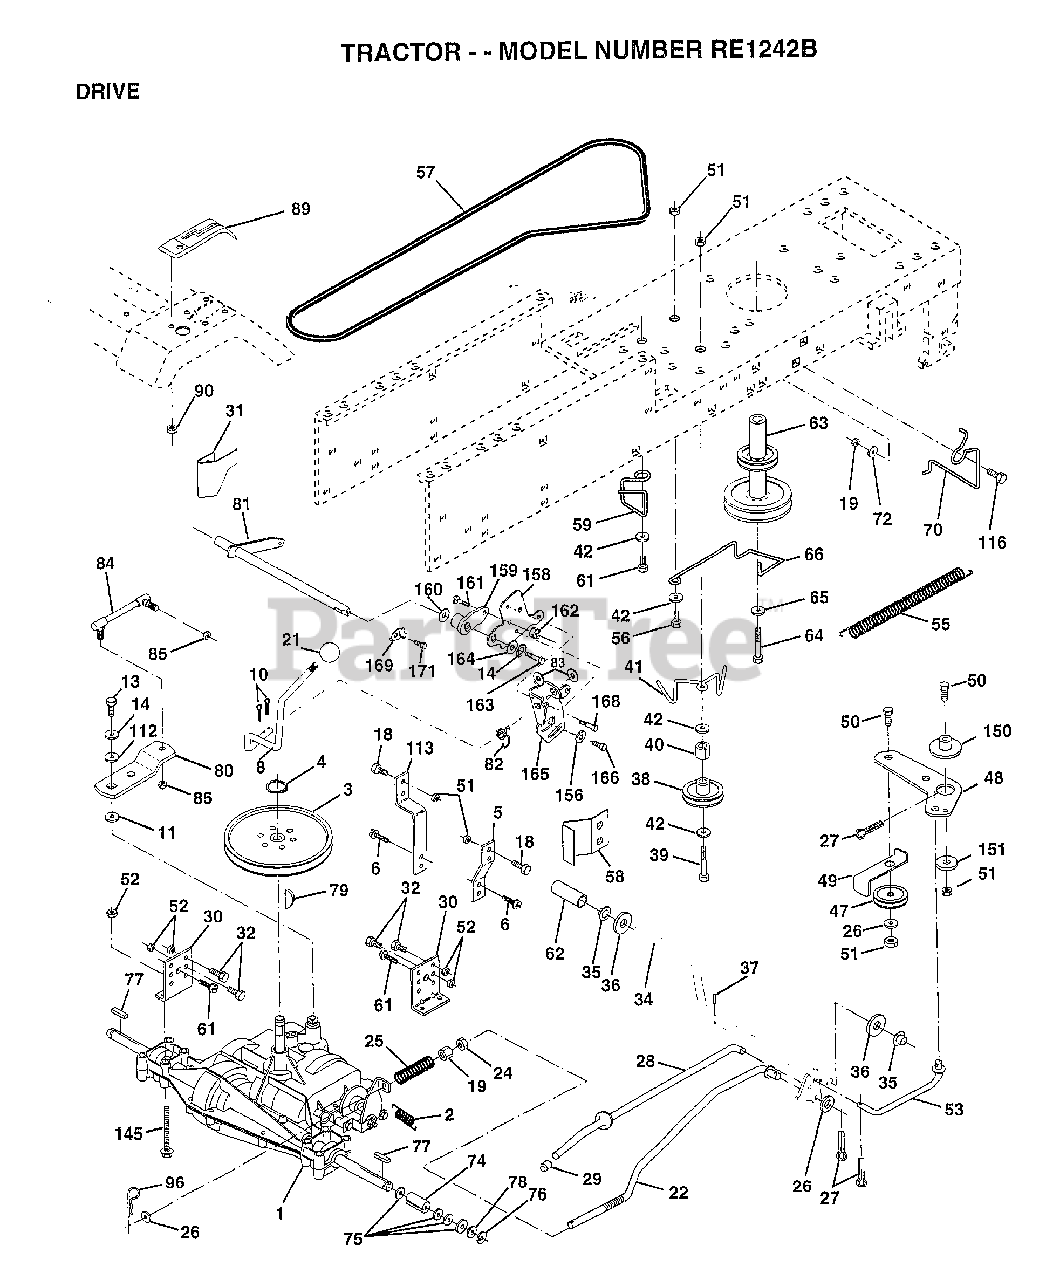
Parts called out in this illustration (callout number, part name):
2	SPRING.BRAKE.RETU
3	PULLEY TRANS
5	STRAP TORQUE
6	SCREW
8	ROD.SHIFT.FENDER.ADJ.LT.CRD
10	PIN COTTER 1/8
11	WASH-SHFT PLT LT
13	BOLT.1/4-28.W/PAT
14	LOCKWASHER
18	BOLT
19	NUT
21	KNOB T (1/2-HOLE)
22	BRAKE ROD
24	NUT
25	SPRING ROD LT
26	WASHER
27	COTTER PIN
28	ROD.BRAKE.PARK.LT
29	PLUNGER CAP T
30	TRANSAXLE MTG BKT
31	"KEEPER,BELT LH T"
32	BOLT
34	SHAFT ASM-PEDAL F
35	NYLON BEARING
36	WASHER LT
38	FLAT IDLER PULLEY
39	BOLT
40	SPACER T
41	"KEEPER,BELT.IDLER FLAT"
42	WASHER
48	BELLCRANK.CLUTCH
49	RETAIN BELT
53	"LINK, CLUTCH T"
55	"SPRING, RETURN LT"
58	"KEEPER,BELT RH T"
59	KEEPER BELT CNTSP
61	SCREW
62	PEDAL COVER T
63	PULLEY.ENGINE
64	BOLT
65	LOCKWASHER
66	KEEPER-BELT
70	KEEPER BELT ENG
72	WASHER
74	SPACER AXLE
75	WASHER
76	E-RING LT
77	SQUARE KEY
78	WASHER
80	"ROD,LINK SHIFT"
81	SHAFT.ASM.CROSS
82	"SPRING,TORSION"
83	WASHER
84	LINK.TRANSAXLE
85	NUT.CNT.LOCK.1/4
89	CONSOLE.SHIFT.LT.5SP.GREY
90	NUT
96	RETAINER M
112	WASHER LT
113	"STRAP,TORQUE"
116	BOLT RDHD 3/8-16
145	BOLT.HEX.FLGHD
150	BUSHING.BELLCRANK.GRD.DR
151	WASHER
156	WASHER.SRRTD.5/16
158	BRKT.SHIFT.MOUNT
159	HUB.SHIFT
160	WASHER
161	BOLT T
164	WASHER.5/8X.281X10GA
165	BRKT.PIVOT.LEVER
166	SCREW.5/16-18X5/8
168	BOLT.SHOULDER.5/16-18X.561
169	PLATE.FASTENING
171	SCREW LT
